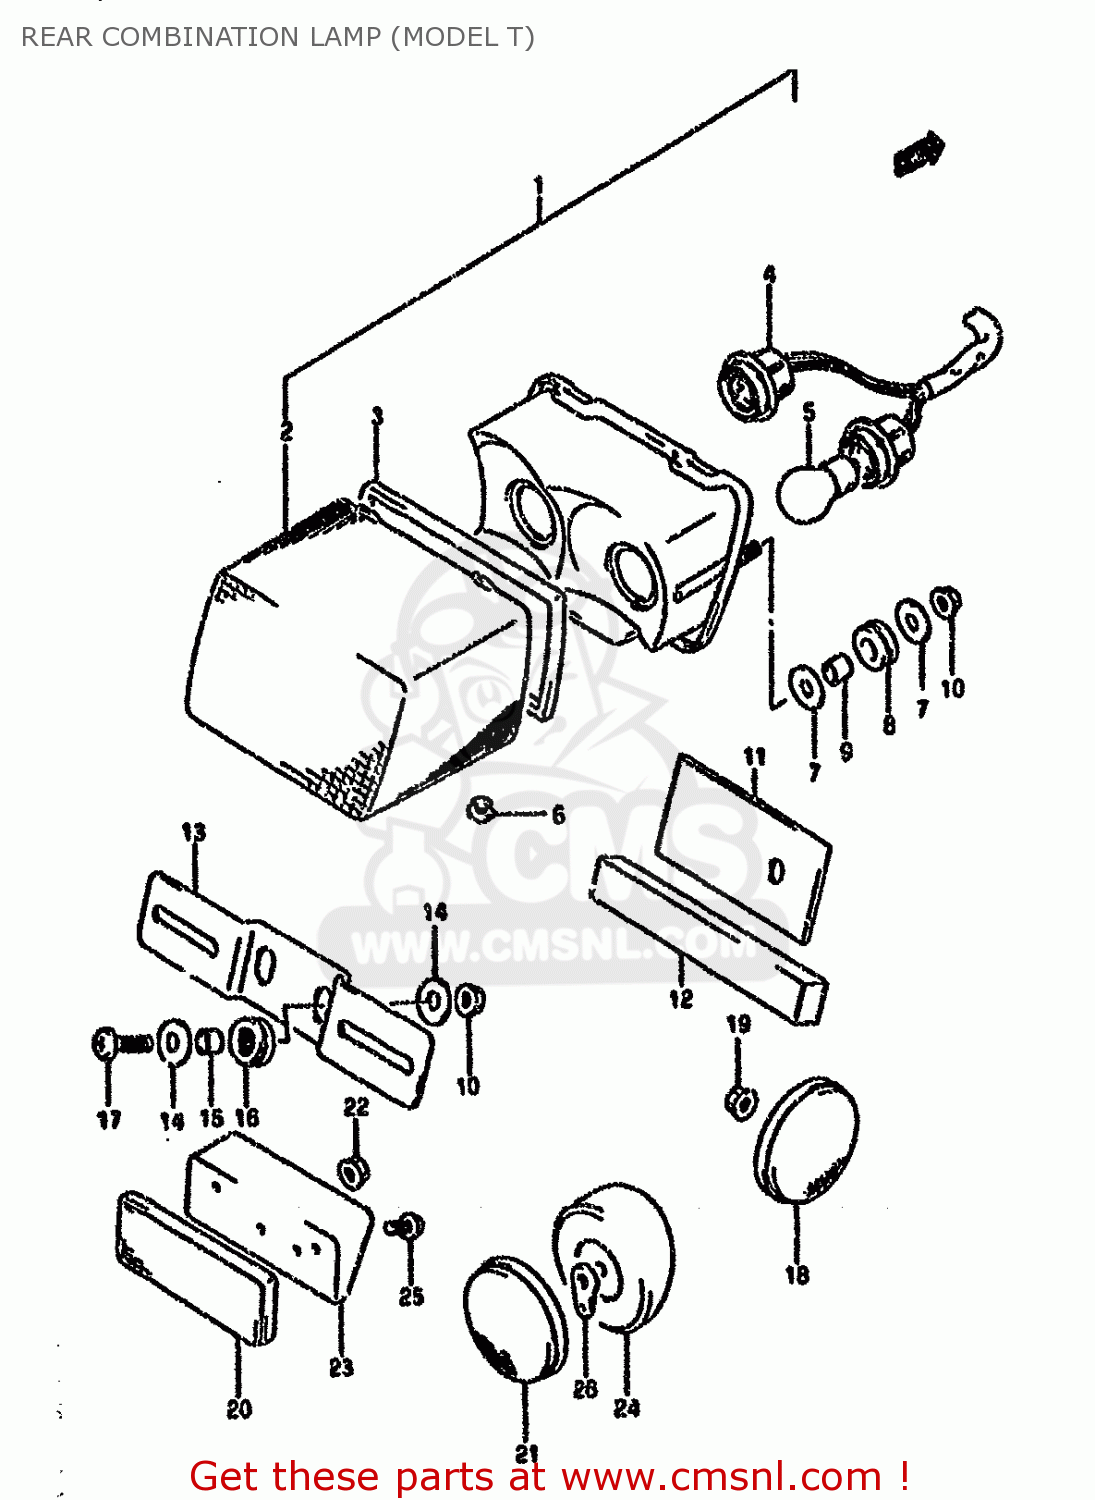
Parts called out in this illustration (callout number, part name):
1	LAMP ASSY,RR COMBINATION
2	LENS
3	GASKET (NAS)
4	SOCKET
5	BULB(12V21/5W)
6	CUSHION
7	WASHER(6.5X20X1.2)
8	CUSHION
9	SPACER
10	NUT
11	CUSHION,UPPER
12	CUSHION,LOWER
13	BRACKET,LICENSE PLATE
14	WASHER(6.5X20X1.2)
15	SPACER
16	CUSHION
17	SCREW
18	REFLECTOR,REFLEX FR
19	NUT
20	REFLECTOR ASSEMBLY,REAR
21	REFLECTOR ASSY,RR
22	NUT
23	SPACER,RR RR
24	SPACER, REAR REFLECTOR
25	SCREW
26	WASHER,RR REFLECTOR
